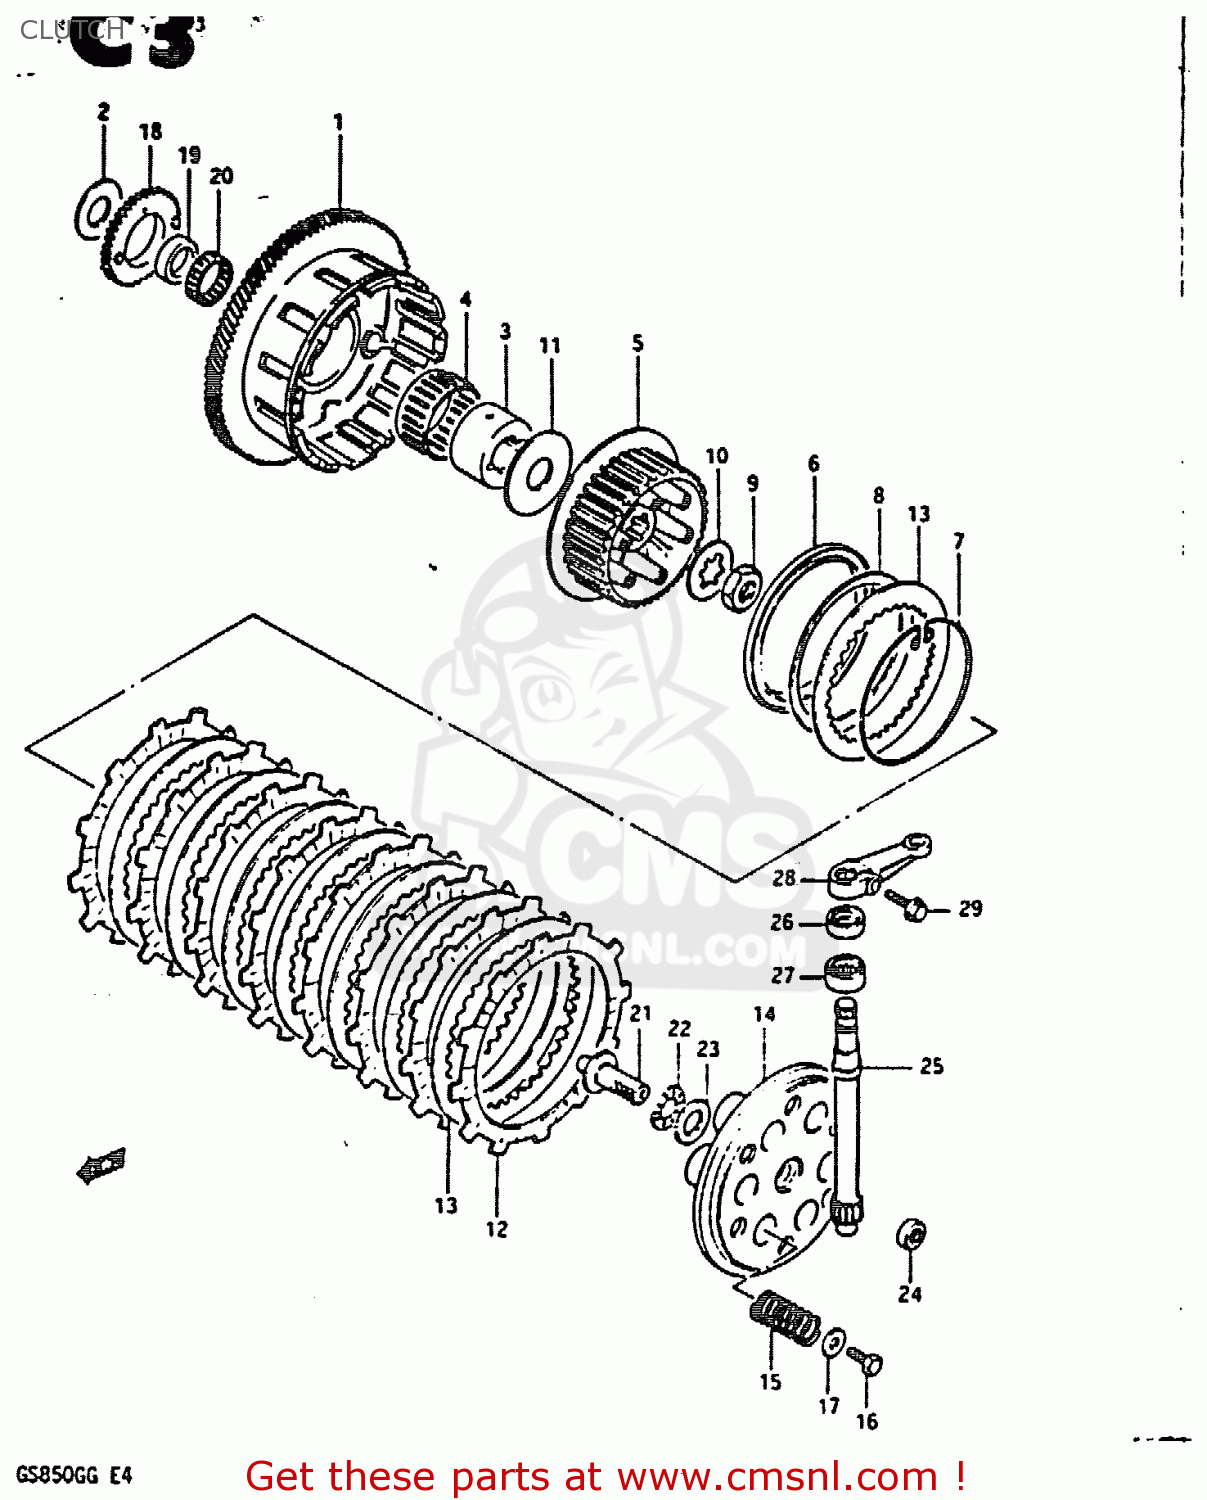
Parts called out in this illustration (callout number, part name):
1	GEAR ASSEMBLY,PRIMARY DRIVE
2	WASHER(25X50X2.5)
3	SPACER
4	BEARING(51X56X28)
5	HUB,CLUTCH SLEEVE
6	SEAT,WAVE WASHER
7	RING,STOPPER
8	WASHER
9	NUT
10	WASHER,LOCK
11	WASHER(25X66X3.5)
12	PLATE,CLUTCH DRIVE (MCA)
13	PLATE,CLUTCH DRIVEN(T:2.0) (NAS)
14	DISC,CLUTCH PRESSURE
15	SPRING
16	BOLT, UPPER
17	WASHER
18	GEAR,ENG OIL PUMP DRIVE(NT:34)
19	SPACER,OIL PUMP DRIVE GEAR
20	BEARING(36X40X10)
21	RACK,CLUTCH RELEASE
22	BEARING(15X28X2)
23	WASHER
24	SEAL,OIL(10X16X5)
25	PINION,CLUTCH RELEASE
26	OIL SEAL
27	BEARING(15X22X12)
28	ARM,CLUTCH RELEASE
29	BOLT,REAR
